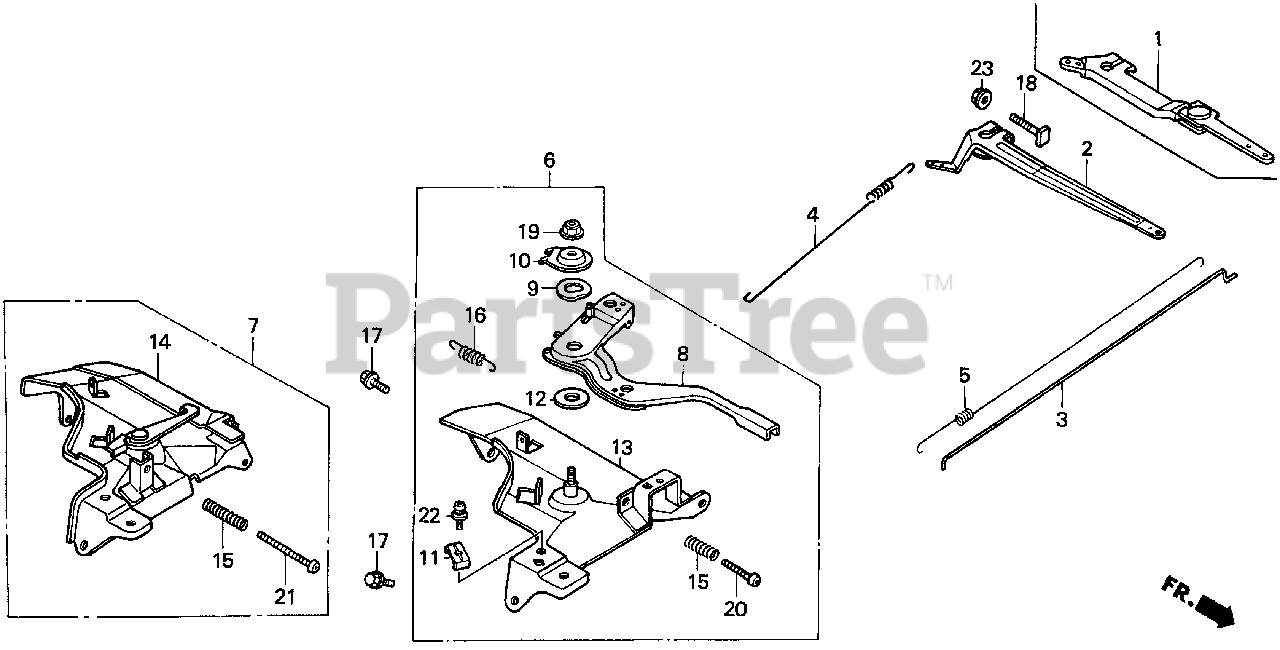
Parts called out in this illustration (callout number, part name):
2	ARM, GOVERNOR
3	ROD, GOVERNOR
4	SPRING, GOVERNOR
5	SPRING, THROTTLE RETURN
6	CONTROL ASSY. (REMOTE)
8	LEVER, CONTROL
9	SPRING, LEVER
10	WASHER, CONTROL LEVER
11	HOLDER, CABLE
12	SPACER, CONTROL LEVER
13	BASE, CONTROL
15	SPRING, CONTROL ADJUSTING
16	SPRING, CABLE RETURN
17	BOLT, FLANGE (6X12) (CT200)
18	BOLT, GOVERNOR ARM
19	NUT, SELF-LOCK (6MM)
20	SCREW, PAN (5X32)
22	SCREW, PAN (5X16)
22	SCREW-WASHER (5X16)
23	NUT, FLANGE (6MM)
